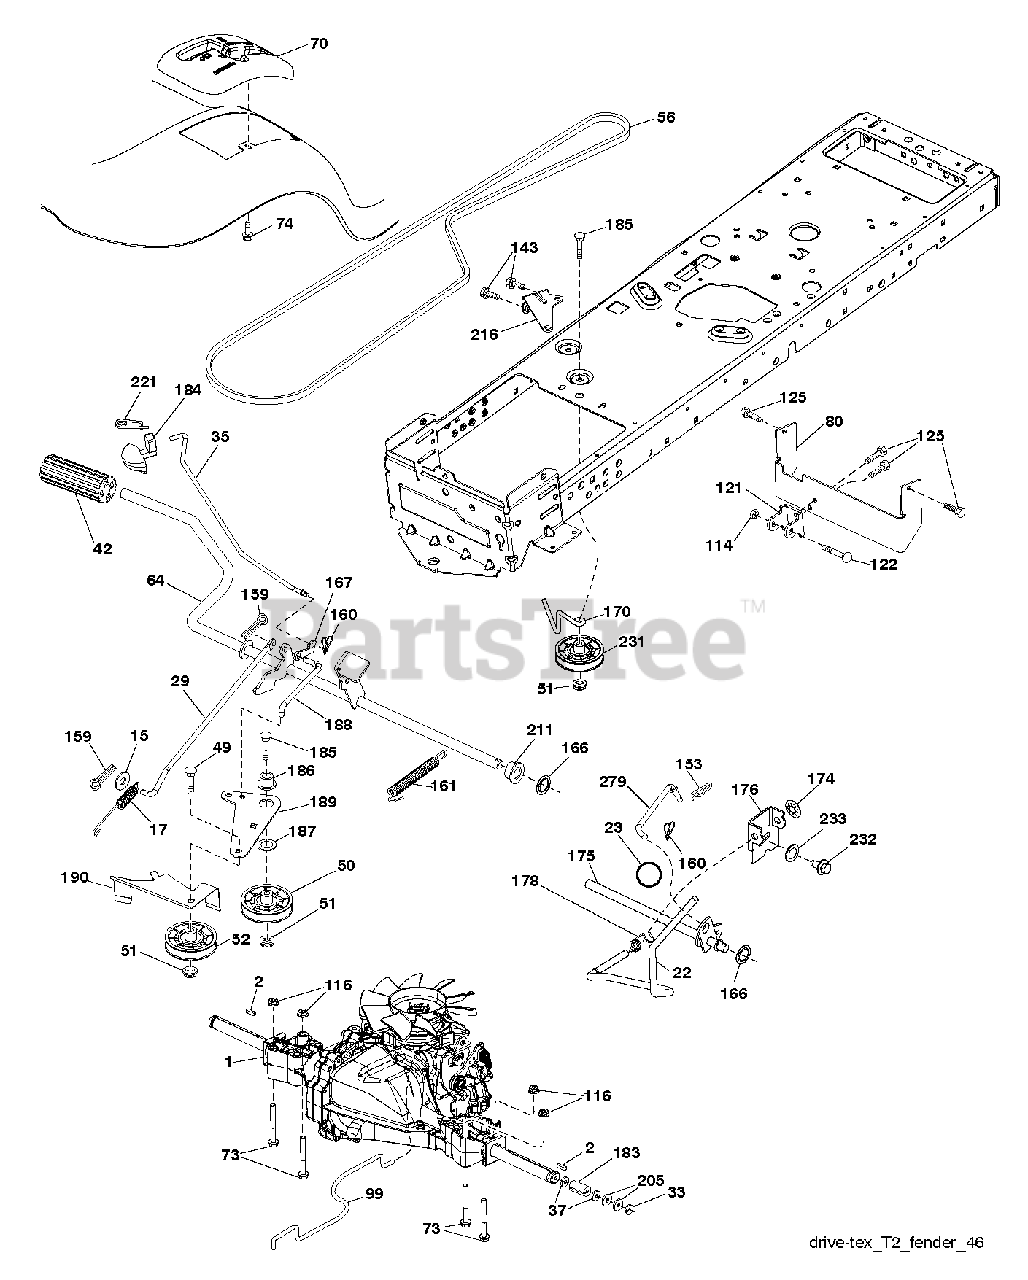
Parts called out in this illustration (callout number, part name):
2	SQUARE KEY
15	WASHER
17	SPRING.BRAKE.HG3000/3500
22	ROD.SHIFT.FENDER.TLT.2006
23	KNOB T (1/2-HOLE)
29	ROD.BRAKE.T2.TEX
33	E-RING LT
35	ROD.CNTRL.PARK.PREDATOR.LT.TEX
49	BOLT
50	IDLER.FLAT.910.OFFSET
51	NUT LOCK FLG 3/8-16 UNC
52	IDLER.V-GROOVE.910.OFFSET
56	BELT.GROUND.DRIVE.T2-HP.CE
64	SHAFT.ASM.PEDAL.BRAKE.
70	CONSOLE.SHIFT.STL.HYD.BLACK
73	BOLT HEX 5/16-18 GR 5
74	SCREW.HI-LO.CONSOLE
80	STRAP.TORQUE.T2
99	ROD.ASM.BYPASS.SPRING.T2.FS
114	NUT.71038.31-18.HEX.NYLOCK
116	NUT LOCK HEX FLANGE 5/16-18
121	BRACKET STRAP TORQUE
122	BOLT.5/16-18X2.5
125	SCREW
143	SCREW LT
159	COTTER PIN
160	RETAINER CLIP
161	SPRING, RETURN LT
166	NUT.PUSH.625
167	LATCH.BRAKE.SPRING
170	KEEPER.CENTER SPAN.1.688
174	NUT.PUSH.500.2006
175	SHAFT.ASM.SHFT.T2.TLT
176	ARM.CLEVIS.ROD.SHIFT
178	SPRING.SHIFT.GT2006
183	SPACER, AXLE PVST
184	Parking Brake Handle
186	SPACER.RETAINER
187	WASHER 12/32X2X10GA
188	LINK.CLUTCH.GROUND.DRIVE
189	BELLCRANK.GROUND.DRIVE.TEX.
190	KEEPER.BELLCRANK.DRIVE
211	BUSHING.SHAFT.BRAKE.HAND
216	BRACKET.PULLEY.IDLER.W/TEX
221	RETAINER.SPRING.CLIP.H
231	IDLER.V-GROOVE.1.688.OFFSET
232	BOLT FIN HEX 7/16-14 X 1
233	WASHER SERRATED
279	LINK.SHIFT.T2
